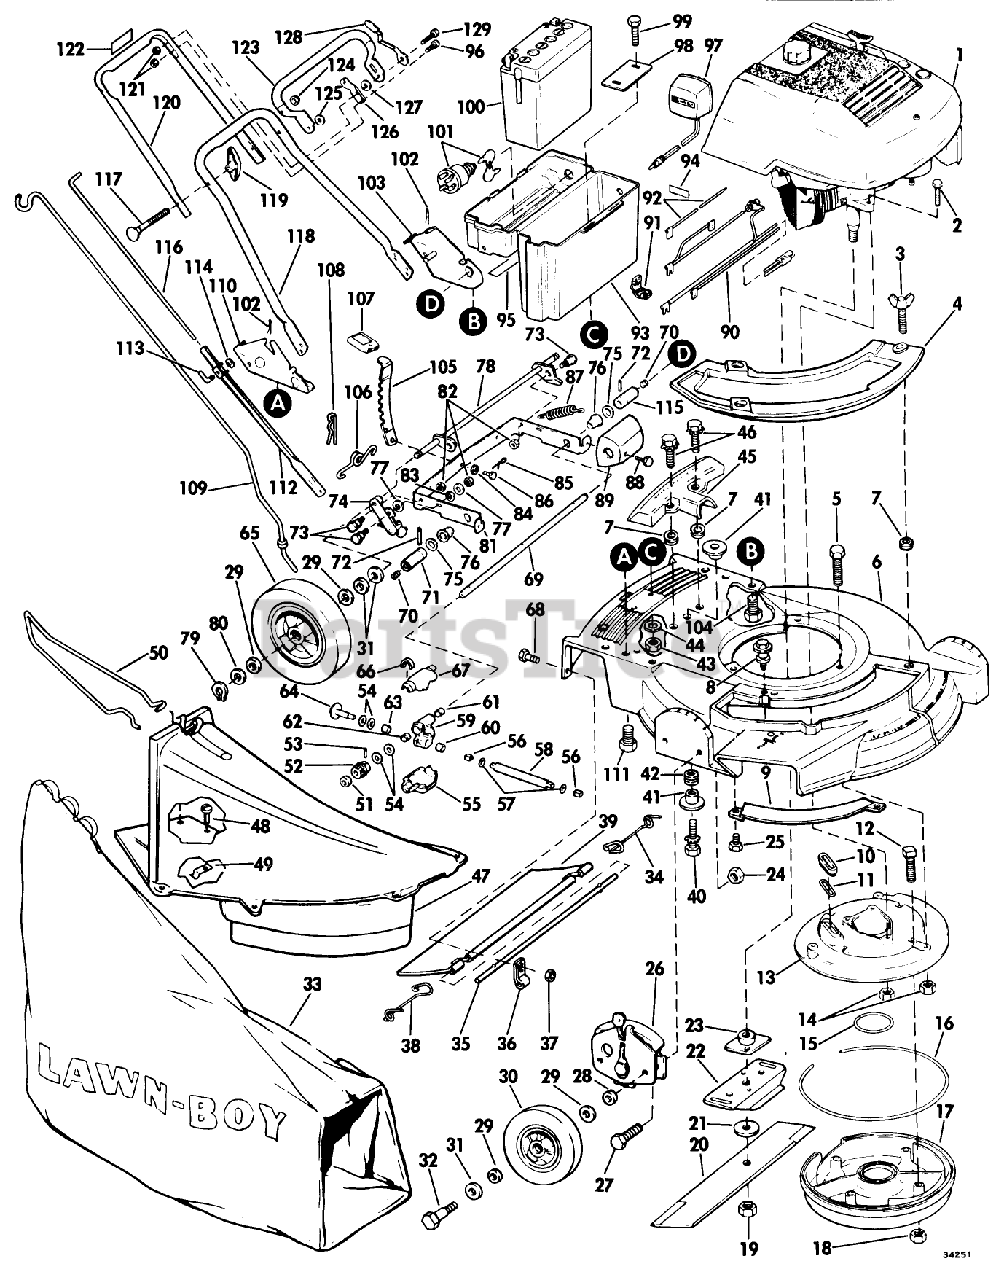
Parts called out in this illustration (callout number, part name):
2	BOLT F
3	WING SCREW LAWRE
5	SCREW V
9	BAR-TOE
10	SLEEVE
11	GASKET S
12	SCREW
14	NUT-LOCK F
16	Gasket Muffler (outside)
18	LOCKNUT E
19	NUT-BLADE
21	WASHER
23	PLATE AND COLLAR ASM
24	NUT
28	WASHER WROUGHT
29	WASHER
31	SPACER
32	BOLT WHEEL
33	ORD LB 89802 WHOLE GOODS
34	SPRIG T/SHLD ASOC
35	ROD 21" ADVANCE
36	CLAMP ROD KMC
38	SPRING;TRAILING SHIELD RH
41	SPACER ECK PRES
42	GROMMET
44	WASHER
45	COVER
46	SCREW SEMS TRM HEX HD
51	WASHER
53	ROLL PIN
54	THRUST WASHER
56	BUSHING
57	O Ring
63	NEEDLE BEARING
67	GEAR COVER UPPER
70	GREASE PLUG
72	PIN
73	BOLT RB&W
77	WASHER S
79	RET RING
80	SPACER
82	STOP NUT
84	WASHER SPRING LAR
86	PIN
87	SPRING
89	GUARD
97	BATTERY CHARGER
102	HAIR PIN
104	SCREW
105	LEVER
106	SPRING N.A.S
107	KNOB
109	ROD GRASSBAG
111	SCREW
116	ROD CONTROL
119	NUT-WING
120	HANDLE
125	WASHER M
128	KNOB & SPRING
129	BOLT RB&W
